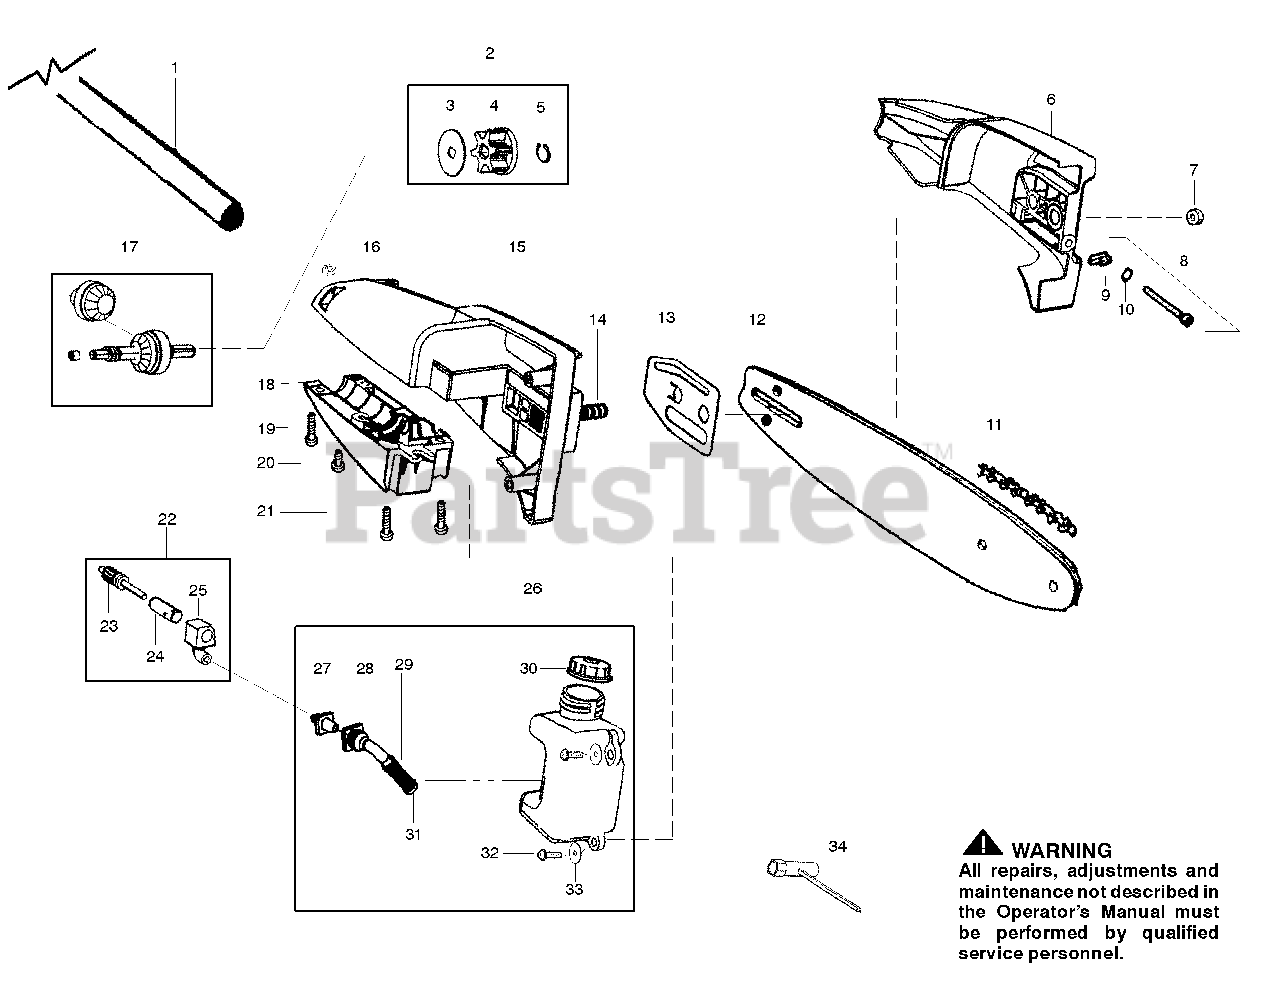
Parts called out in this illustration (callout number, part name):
1	Assy-Driveshaft
2	Kit-Sprocket Assy.
4	Sprocket
5	Retainer-Sprocket
6	Assy-Bar Clamp
7	Nut-Bar Mounting
8	Kit-Bar Adjust
9	Pin-Bar Adjust
10	Retainer-Bar Adjust
11	Accy-Chain-8'
13	Plate-Bar pad
14	Bolt-Bar
15	Hsg.-Upper
17	Kit-Gear Assy
18	Hsg.-Lower
20	Screw-Align
22	Kit-Oil Assy
23	Assy-Gear Plunger
25	Block-Oil
26	Assy-Oil Tank
27	Fitting-Oil Line
28	Intake-Oil Line
29	Filter-Oil
30	Cap-Oil
31	Plug-Oil Filter
34	Wrench-Bar
